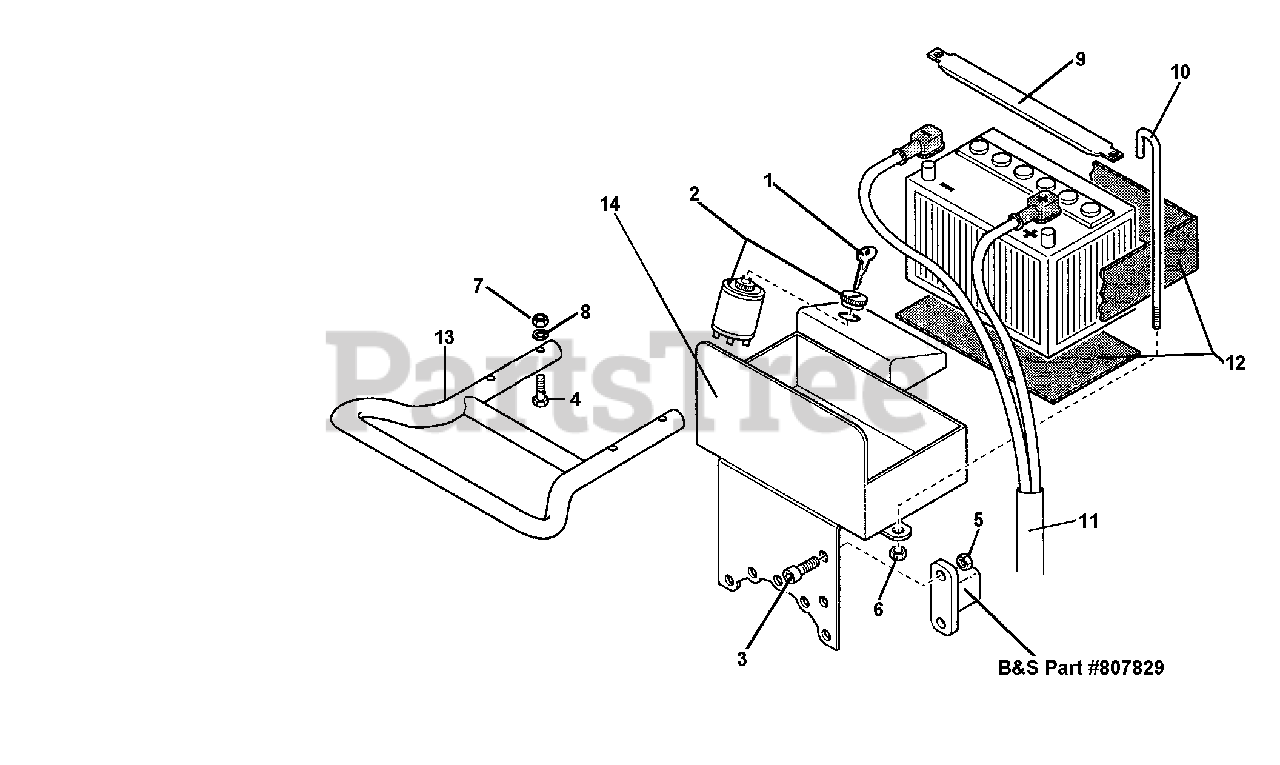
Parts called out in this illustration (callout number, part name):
3	SCREW TE M6X10
4	SCREW M8X70
6	NUT, SELF LOCKING M6
7	NUT, SELF LOCKING M8
8	FLAT WASHER 8.4
9	BATTERY BRACKET
10	BATTERY TIEROD
11	ELECTRIC START CABLES 5HP & 8HP B&S
12	BATTERY PADS
13	BUMPER, 8HP B&S IP
14	BATTERY SUPPORT, 5HP & 8HP B&S
